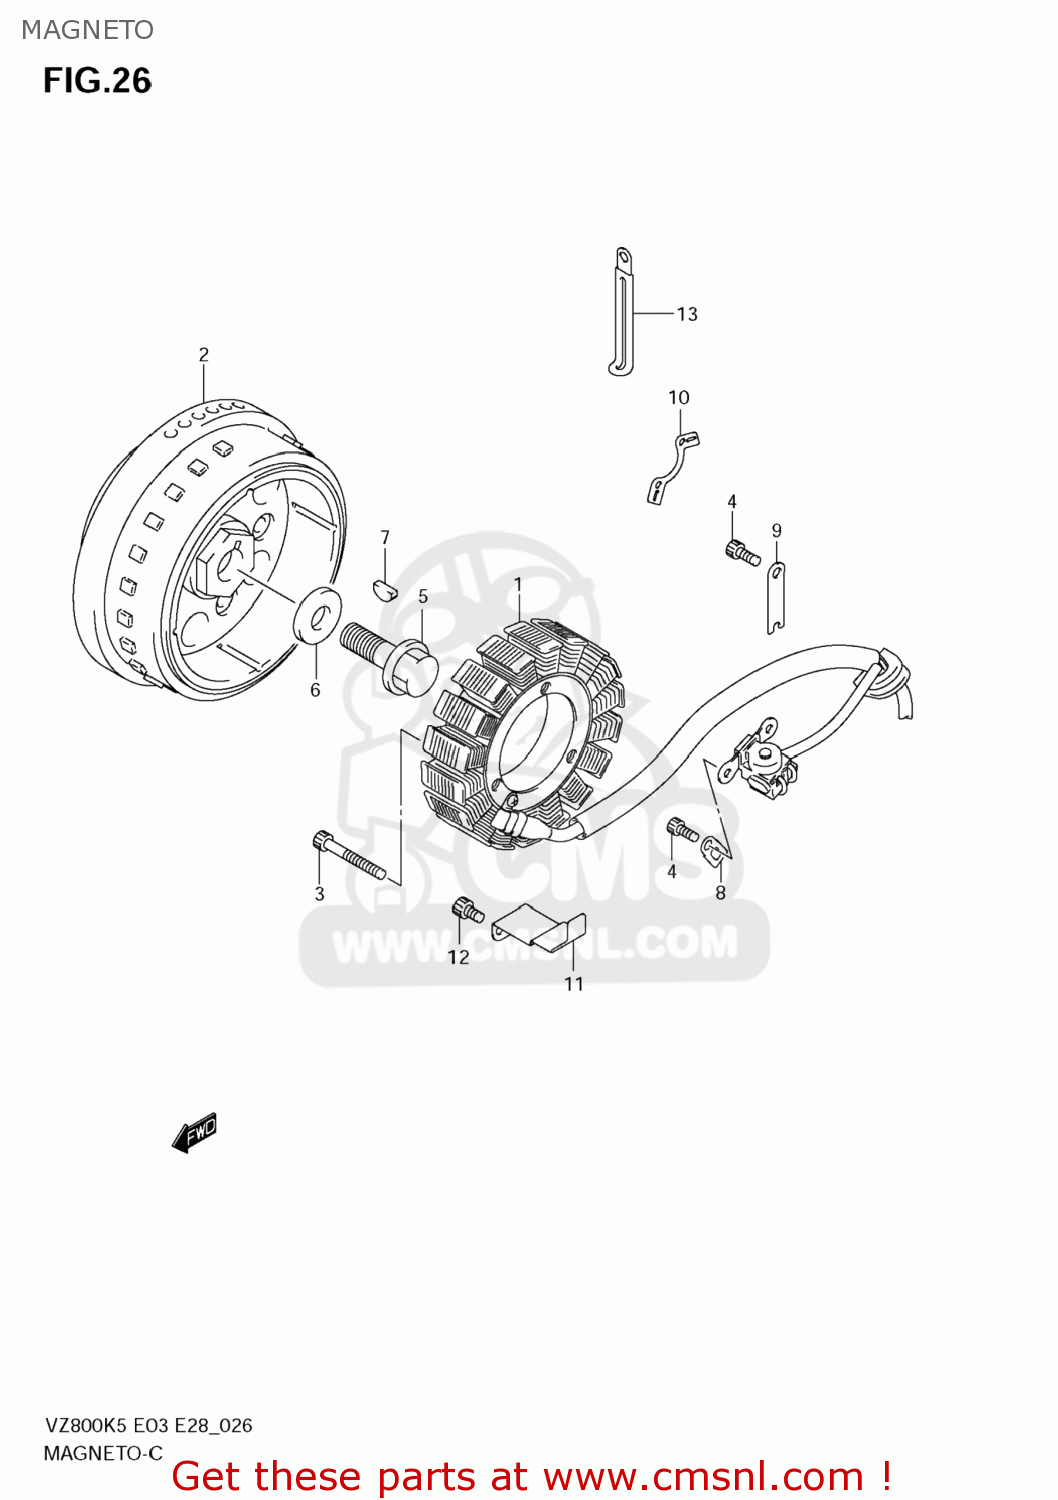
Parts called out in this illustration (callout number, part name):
1	STARTER ASSY
2	ROTOR ASSY
3	BOLT
4	BOLT
5	BOLT(14X43)
6	WASHER(14X29X4)
7	KEY
8	CLAMP,GENERATOR LEAD WIRE
9	CLAMP NO.1,MAGNETO READ WIRE
10	CLAMP,MAGNETO LEAD
11	CLAMP,MAGNETO LEAD WIRE
12	BOLT
13	CLAMP(L:80)
